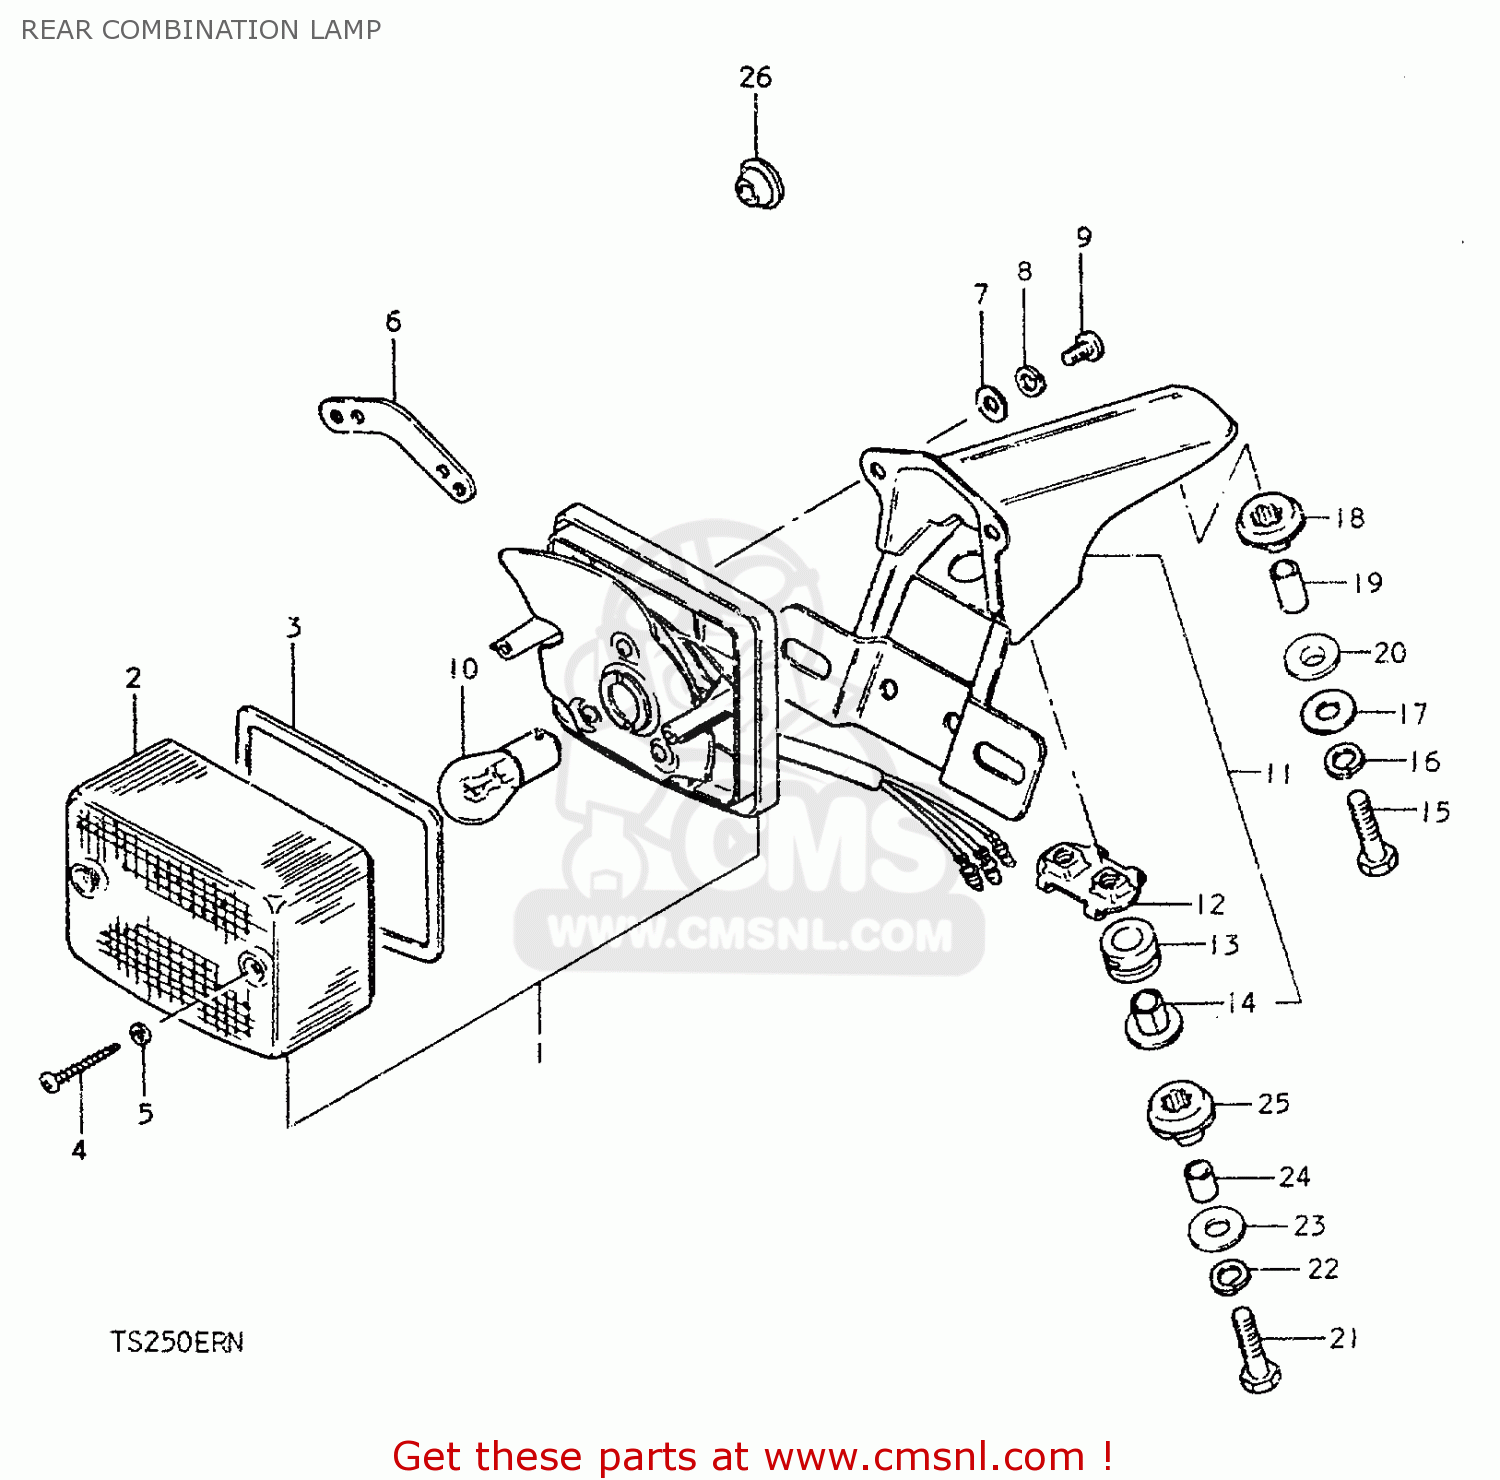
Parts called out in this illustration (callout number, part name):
1	LAMP UNIT,REAR COMBINATION
2	LENS
3	GASKET (NAS)
4	BOLT
5	GASKET (NAS)
6	PLATE,REAR COMBINATION LAMP
7	WASHER,5MM
8	WASHER,LOCK
9	SCREW
10	BULB(6V32/3CP,STANLEY)
11	BRACKET UNIT,TAIL LAMP
12	PLATE
13	CUSHION
14	SPACER
15	BOLT
16	LOCK WASHER
17	WASHER (6.5X20X1.2)
18	CUSHION
19	SPACER
20	CUSHION
21	BOLT
22	LOCK WASHER
23	WASHER (6.5X20X1.2)
24	SPACER
25	CUSHION
26	GROMMET
